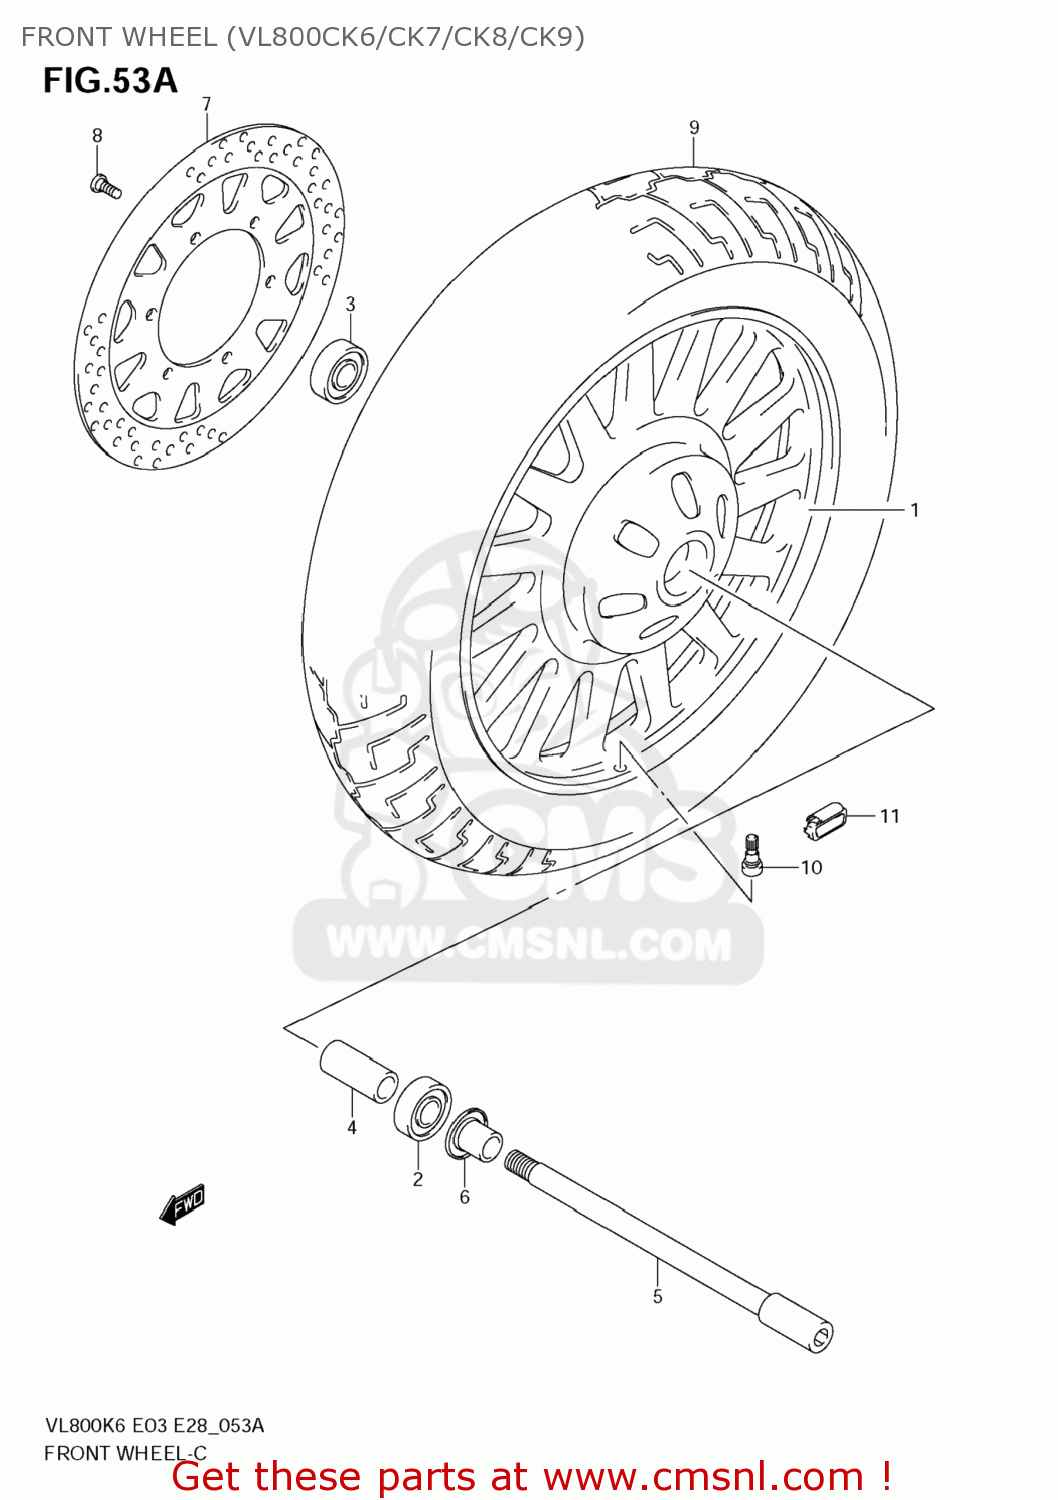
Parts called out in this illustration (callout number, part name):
1	WHEEL,FR(16M/CXMT3.00)
2	BEARING
3	BEARING
4	SPACER(17.5X25X102)
5	AXLE,FR
6	SPACER,FR AXLE,R
7	DISC,FR BRAKE
8	BOLT(8X21)
9	TIRE,FR(130/90 16M/C 67H)
10	VALVE ASSY,WHEEL RIM(TR412)
11	WEIGHT,WHEEL BALANCE 10G
